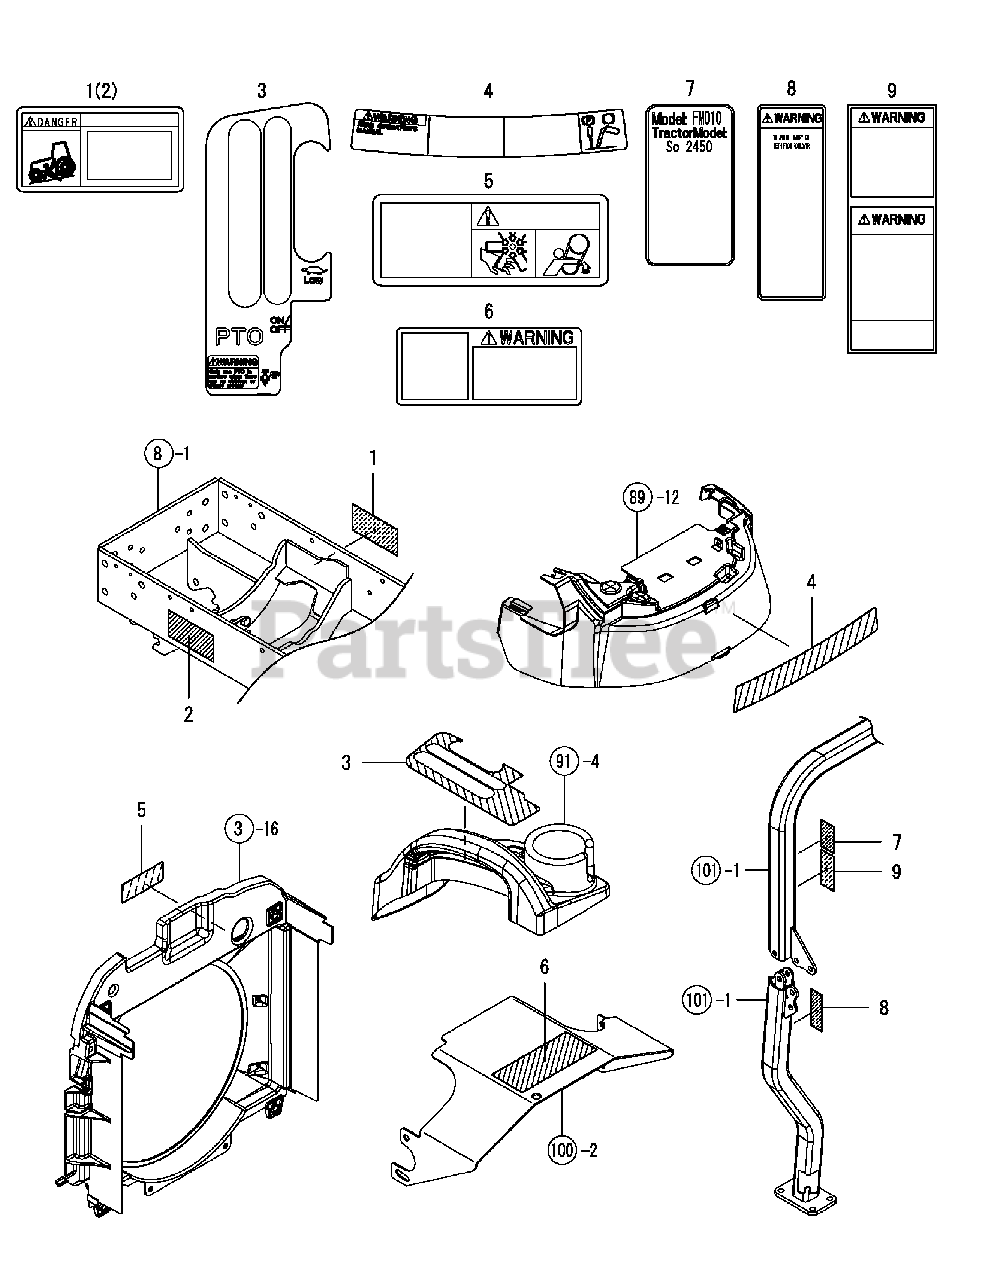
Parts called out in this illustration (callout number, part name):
1	LABEL,DANGER, START
2	LABEL,WARNIBG, STOP
3	LABEL, LEVERGUIDE L
4	LABEL,CAUTION, GENERAL
5	LABEL,WARNING, FAN
6	LABEL, P.T.O. WARNING
8	LABEL, WARNING ROPS
9	SAFETY DECAL, ROPS
